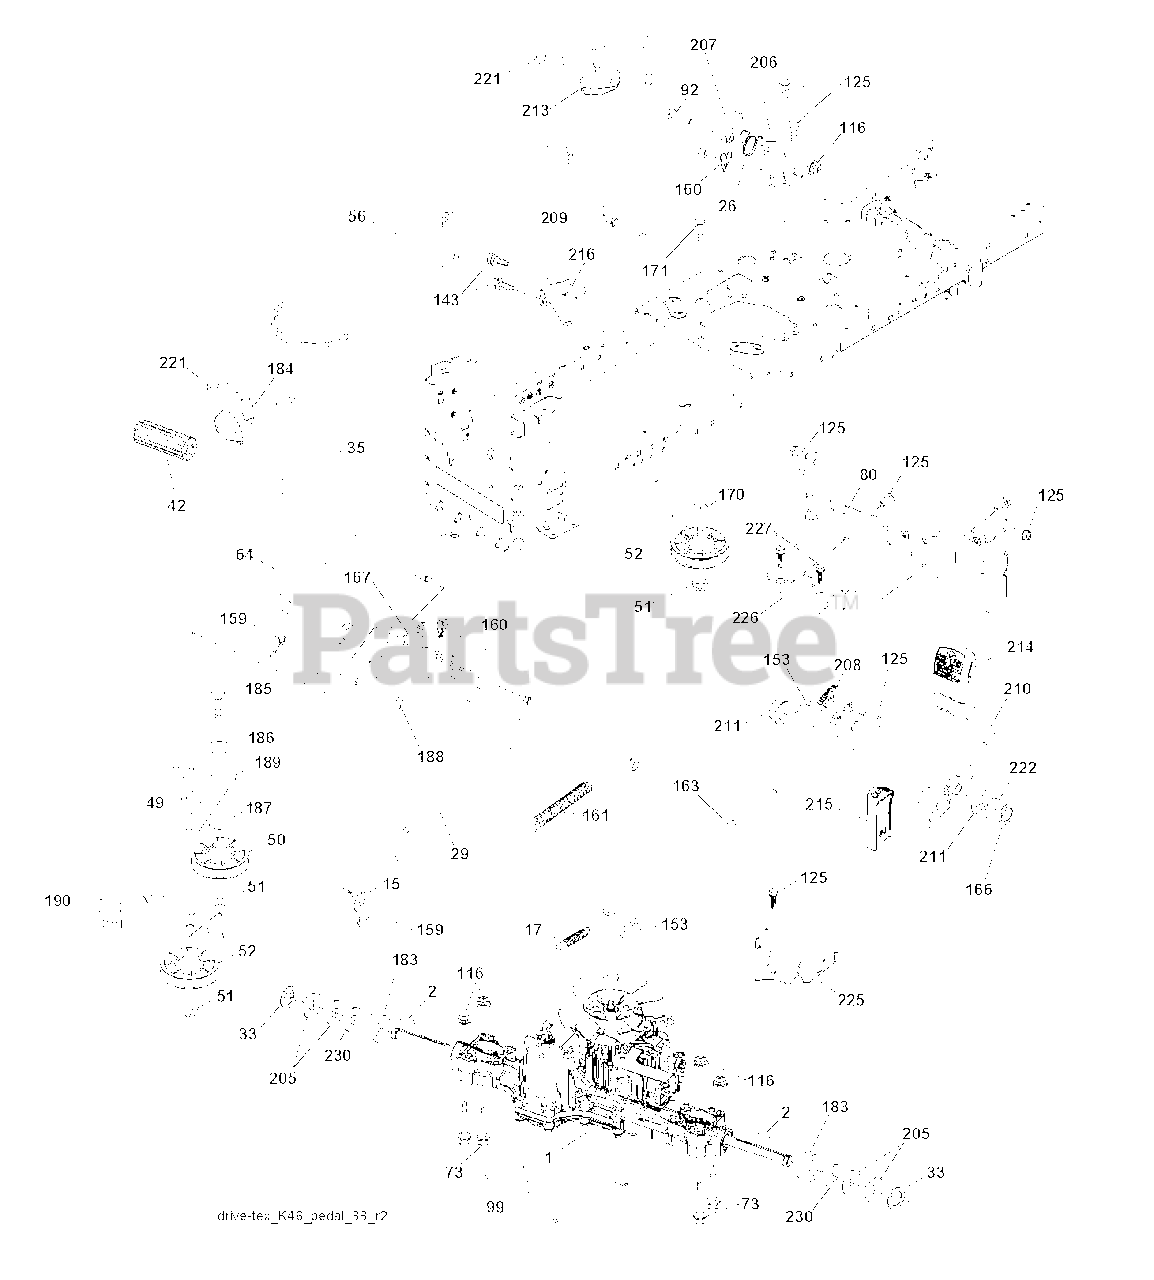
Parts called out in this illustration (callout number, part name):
2	SQUARE KEY
15	WASHER
17	SPRING.BRAKE.K46.GREEN
26	SPRING.RETURN.CRUISE
29	ROD.BRAKE.K46
35	ROD.BRAKE.PARTK.HUSQ.TEX
42	PEDAL COVER T
50	IDLER.FLAT.910.OFFSET
51	NUT LOCK FLG 3/8-16 UNC
52	IDLER.V-GROOVE.910.OFFSET
56	V-BELT.MOWER.92.40.42/K46
64	SHAFT.ASM.PEDAL.BRK.CNTR
73	BOLT
80	STRAP.TORQUE.K46.K57R.TT
92	BOLT
99	ROD.SPRING.BYPASS.K46.LT.Z
116	NUT LOCK HEX FLANGE 5/16-18
125	SCREW
143	SCREW LT
153	RETAINER M
159	COTTER PIN
160	RETAINER CLIP
161	SPRING, RETURN LT
163	ROD.CONTROL.K57R.K46
166	NUT.PUSH.625
167	LATCH.BRAKE.SPRING
170	KEEPER.V-IDLER.CENTER.
171	BOLT
183	SPACER AXLE
184	RB HANDLE.PARKG.BRK.HUS/PRED
186	SPACER.RETAINER
187	WASHER 12/32X2X10GA
188	RP LINK.CLUTCH.GROUND.DRIVE
189	BELLCRANK.GROUND.DRIVE.TEX.
190	KEEPER.BELLCRANK.DRIVE
206	BRKT.MOUNT.LATCH.CRUIS
207	LATCH.CONTROL.CRUISE
208	GEAR.SECTOR.CONTROL.CR
209	ROD.CONTROL.CRUISE.GT.
210	ROCKER.ASM.PEDAL.CONTR
211	BEARING.NYLON
213	KNOB.CONTROL.CRUSIE.HU
214	PEDAL.FORWARD.PAD.TEX
215	PEDAL.REVERSE.TEX.GT.4
216	BRACKET.PULLEY.IDLER.W/TEX
221	RETAINER.SPRING.CLIP.H
222	WASHER 21/32 X 1-1/4 X 10 GA.
225	KEEPER.BELT.TRANSAXLE.K46
226	BRACKET.MOUNT.TORQUE.K46.TLT
227	SCREW
230	WASHER.HARDENED
